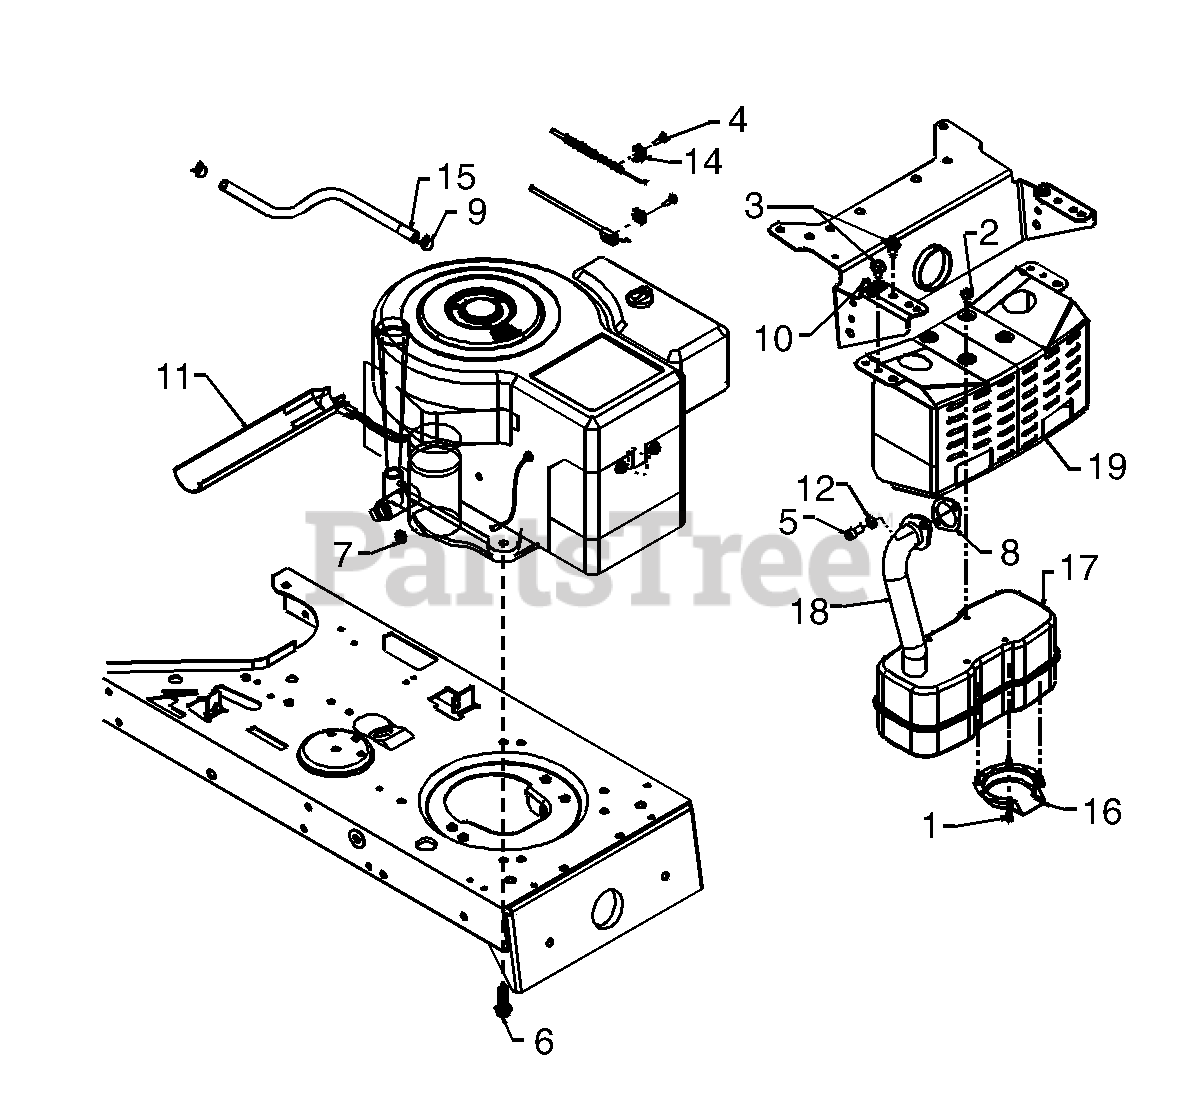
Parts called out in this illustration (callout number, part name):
1	Hex Tap Scr. #8-32 x .38" Lg.
2	Hex TT-Tap Scr. 1/4-20 x .5" Lg.
3	Hex TT-Tap Scr. 5/16-18 x .62"
4	Hex Wash. Scr. #10-32 x .62"
5	Socket Head Scr. 5/16-18 x .62"
6	Hex TT-Tap Scr. 3/8-16 x 1.25"
7	Hex Sems Scr. 1/4-20 Thd.
8	Gasket
9	Hose Clamp
10	Clamp
11	Oil Drain Sleeve
12	Lock Washer 5/16" I.D.
14	Casing Clamp
15	Fuel Line 12" Lg.
16	Muffler Deflector
17	Muffler
18	Exhaust Pipe
